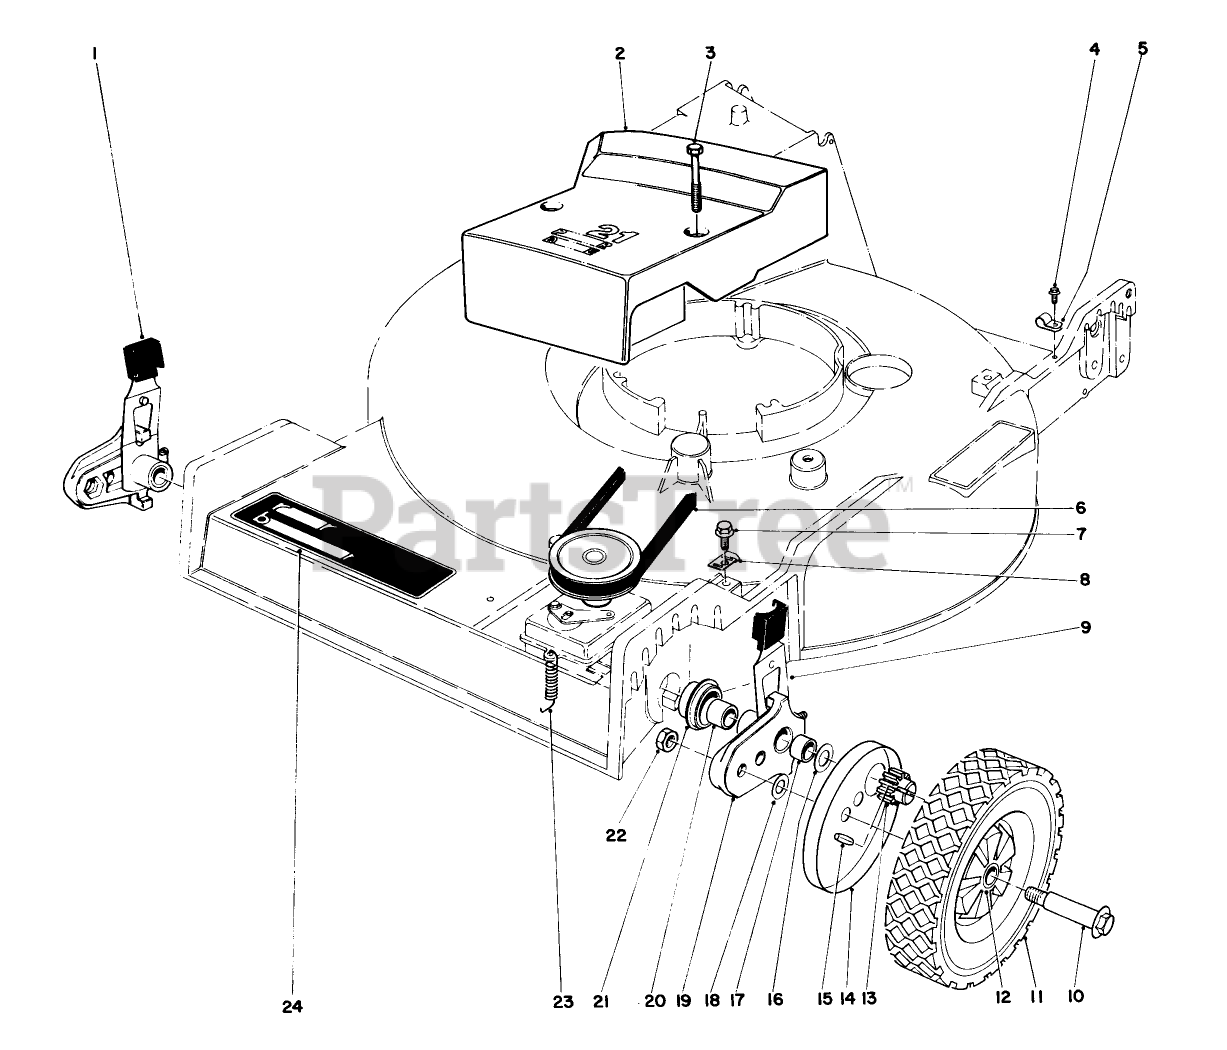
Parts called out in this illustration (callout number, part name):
1	KNOB-ARM
4	SCREW
5	CLAMP-CABLE
6	BELT-V
7	SCREW-THD ROLL, HWH
10	BOLT-WHEEL
11	WHL/GEAR/TIRE PKG
12	BUSHING
13	PINION GEAR 15T
17	Bushing
18	WASHER
19	PIVOT ARM ASM
23	TENSION SPRING
